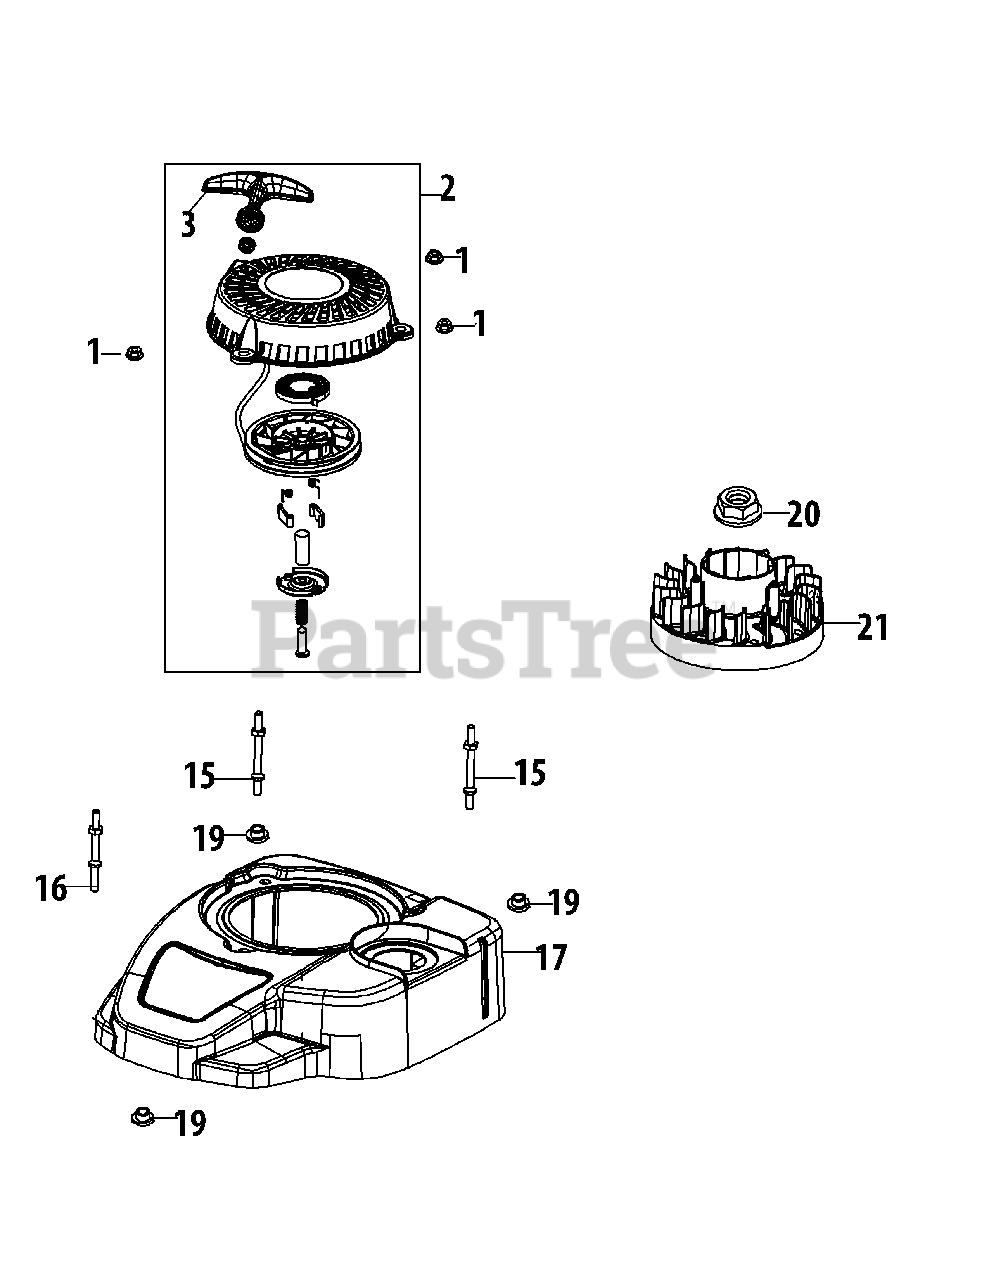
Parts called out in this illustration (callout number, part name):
1	Nut M6X10Mm Starter/Carb/Muff
2	Starter Recoil Assembly
3	Starter Handle
15	Starter/Shroud Rear Stud M6×75
16	Starter/Shroud Front Stud M6×73
17	Engine Shroud Assembly
19	Engine Shroud Spacer
20	Flywheel Nut M14
21	Flywheel
